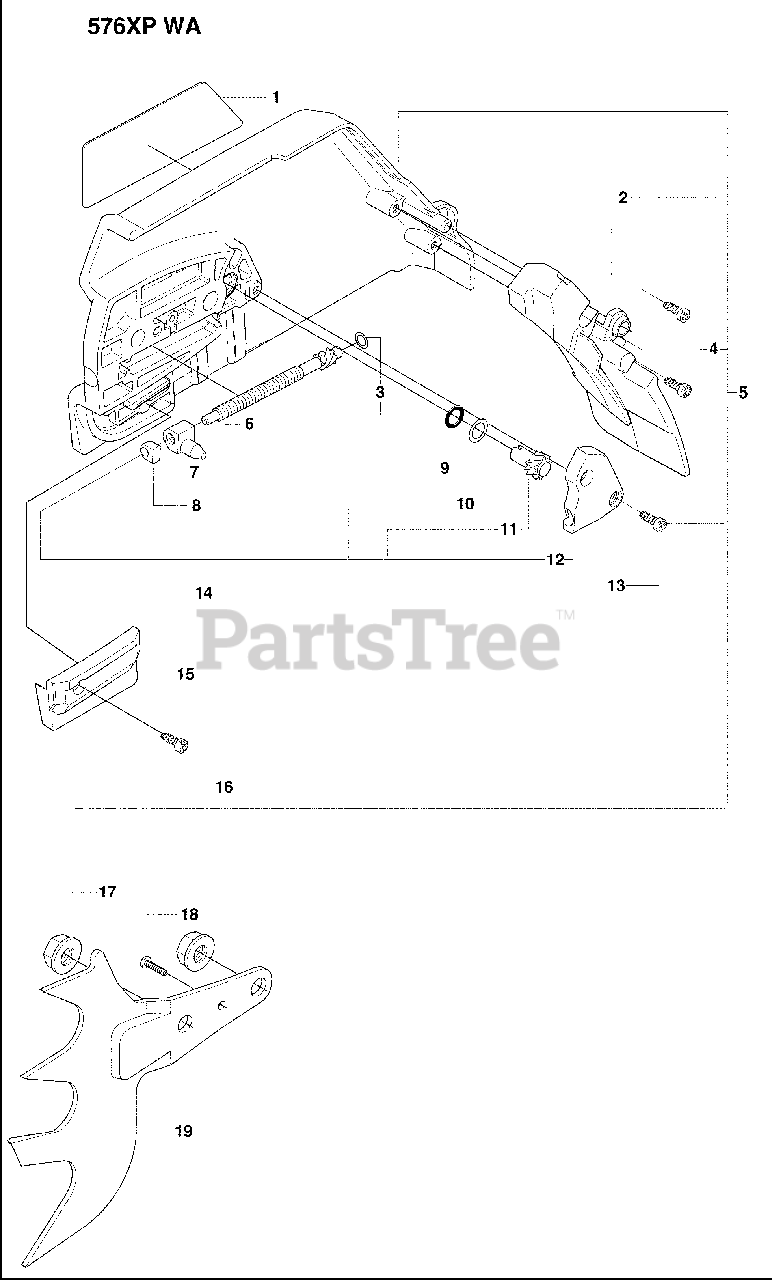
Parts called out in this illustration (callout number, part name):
5	Clutch Cover Assembly
6	Worm Screw with Adjuster
11	Worm Wheel
14	Chain Tensioner Kit
15	Chain Guide
17	Flange Hex Nut, M8
19	Felling Dog
